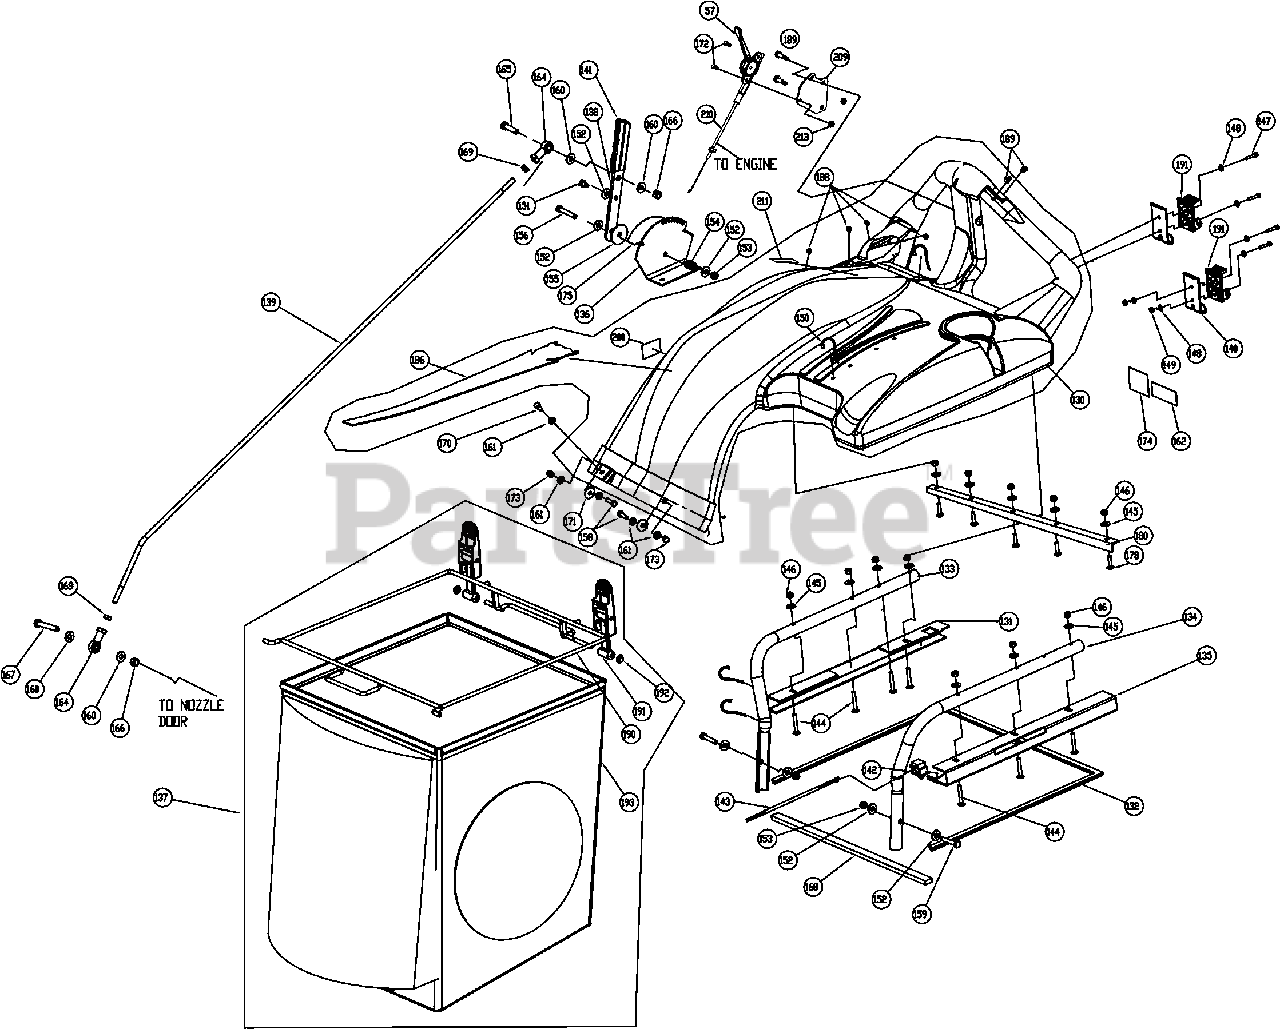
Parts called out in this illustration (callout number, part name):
57	CONTROL THROTTLE
130	HOOD ASSY W/ LABEL MV VAC
131	BRACKET BAG CHANNEL RH W/SEAL MV VAC
132	SEAL BAG MV VAC
133	TUBE HANDLE BRACE RH MV VAC
134	TUBE HANDLE BRACE LH MV VAC
135	BRACKET BAG CHANNEL LH
136	BRACKET NOZZLE DOOR ADJ W/LABEL MV VAC
137	BAG ASSEMBLY MV VAC
138	BAR LIFT NOZZLE DOOR W/ GRIP MV VAC
139	ROD LIFT NOZZLE DOOR SP VAC
140	PLATE BAG LATCH MV VAC
141	GRIP LEVER LIFT
142	SWITCH INTERLOCK VAC
143	HARNESS WIRE ASSY MV VAC
144	BOLT CARRIAGE 1/4-20 X 1.75
145	WASHER 1/4" FC ZP
146	NYLON INSERT LOCKNUT 1/4-20 UNC
147	SCREW HEX HEAD #10-24 X 1"
148	WASHER #10 SAE ZP
149	NYLON INSERT LOCKNUT 10-24 UNC
151	PIN SCREW 1/4-28
152	WASHER 5/16 FLATWASHER Z/P
153	NYLON INSERT LOCKNUT 5/16-18 UNC
154	SPRING LEVER GZ
155	FIBRE WASHER
156	SCREWCAP 5/16"-18 X 2 ZP
158	SCREWCAP 1/4-20X1" ZP
159	SCREWCAP 5/16-18 X 1.75 ZP
160	WASHER 3/8" FC
161	WASHER 1/4" SAE ZP
162	LABEL SAFETY PROTECT READ MANUAL
164	ROD END BALL JOINT 3/8 NF
165	SCREW CAP 3/8-16X1 1/2 ZP
166	NYLON INSERT LOCKNUT 3/8-16 UNC
167	SCREWCAP 3/8"-16X2 1/2" ZP
168	SEAL BAG FRONT HOOD 20.5 LONG
169	NUT REG 3/8-24 NF
170	SCREWCAP 1/4"-20X3/4" HCS ZP
171	WASHER FENDER 1/4 ZP
172	SCREW MACH FLAT HD PHIL #10-24
173	NUT ACORN 1/4-20
174	LABEL DANGER FLYING DEBRIS
175	LABEL NOZZLE DOOR MV VAC
178	BOLT CARRIAGE 1/4-20 X 3/4"
180	BRACKET HOOD FRONT STRAIGHTENER
188	PLUG SNAP RIVET 0.166 DIA
189	PLUG SNAP RIVET 0.232 DIA
190	ROD BAG WA MV VAC
191	LATCH RUBBER ASSEMBLY MV VAC
192	PAL NUT 0.312
193	BAG DEBRIS MV VAC
209	PLATE MV THROTTLE CONTROL
210	CABLE THROTTLE CONTROL 52"
211	LABEL THROTTLE
212	SCREW PLASTITE 1/4"-10 X 3/4" HWH ZP
213	NUT LOCK LT #10-24 HEX
